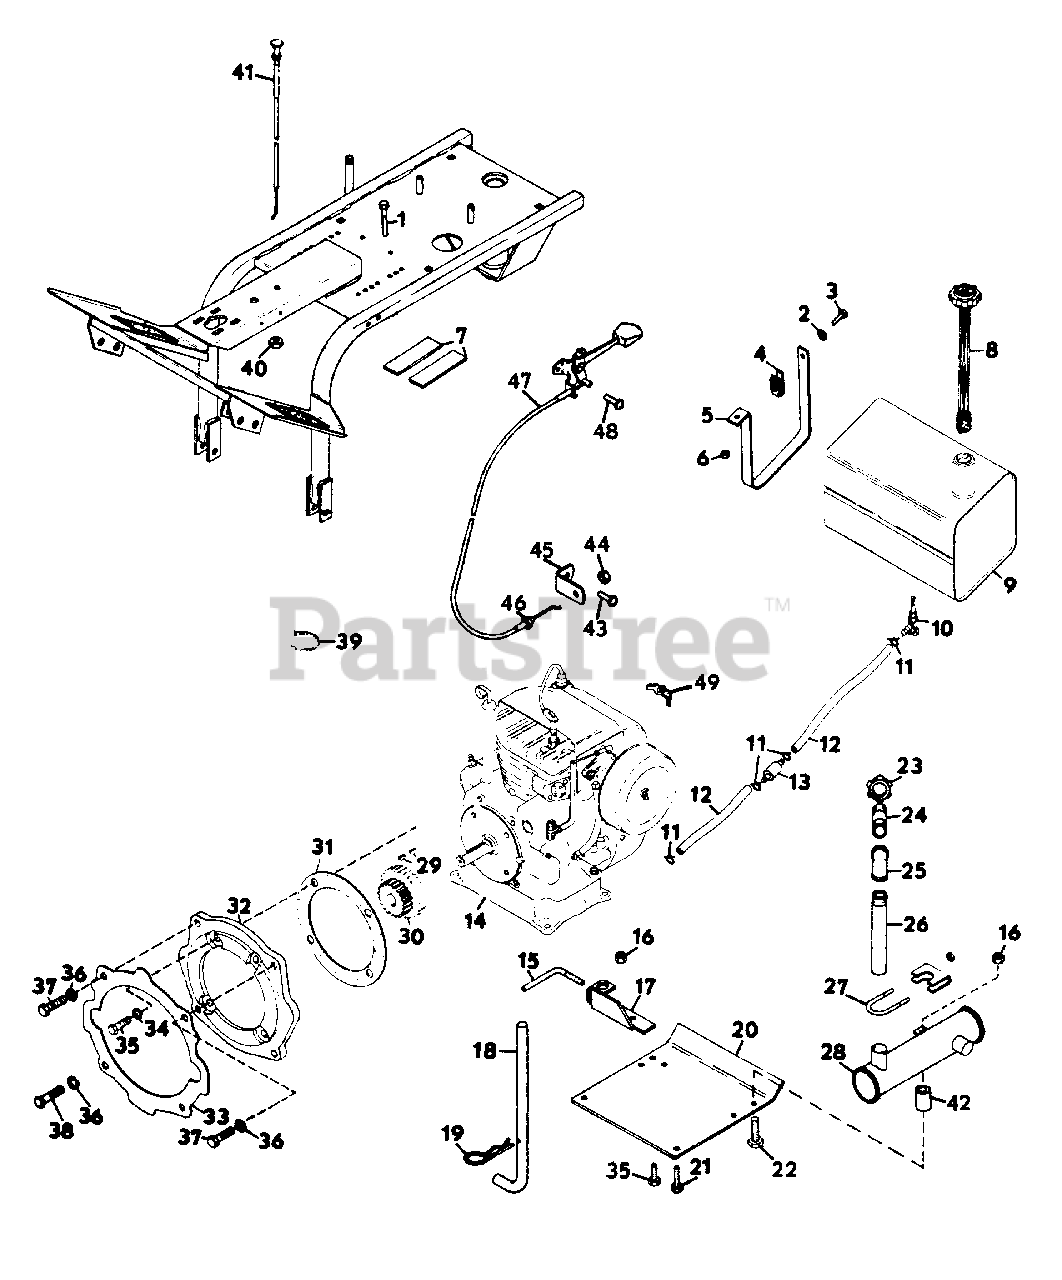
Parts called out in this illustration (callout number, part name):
1	BOLT, HEX 5/16-18X1.25
2	WASHER, FLAT .312X.734X.065
3	BOLT, HEX 5/16-18X.75
4	NUT, RETAINER
5	STRAP, GAS TANK
6	NUT, LOCK 5/16-18
7	PAD, GAS TANK
8	GAUGE, FUEL
9	TANK, FUEL
10	VALVE AND STRAINER
11	CLAMP, FUEL HOSE
12	LINE, FUEL
13	FILTER, FUEL
14	ENGINE, 16-HP KOHLER
15	HANDLE, ADJUSTING
16	NUT, LOCK 3/8-16
17	STAND, SUPPORT
18	STAND, KICK
19	PIN, HAIR
20	PLATE, SKID
21	BOLT, HEX 3/8-16X1.50
22	BOLT, HEX 3/8-16X1.75
23	NUT, CONDUIT 1.25" PIPE
24	NIPPLE, 1.25 PIPE
25	ELBOW, 1.25 PIPE
26	NIPPLE, 1.25 PIPE 8.6 LG.
27	CLAMP, MUFFLER
28	MUFFLER, 16-HP ENGINE
29	KEY, WOODRUFF 5/32X.625
30	GEAR, 10/12 DP 21/30 TEETH
31	GASKET, ENGINE TO ADAPTOR
32	ADAPTOR, ENGINE
33	GASKET, CHASSIS TO ADAPTOR
34	WASHER, LOCK 3/8
35	BOLT, HEX 3/8-16X1.00
36	WASHER, LOCK 7/16
37	BOLT, HEX 7/16-14X1.50
38	BOLT, HEX 7/16-14X1.25
39	TIE, CABLE
40	NUT, JAM 3/8-24 HEX
41	CONTROL, CHOKE
42	BUSHING, .407X.625X.812
43	SCREW, MACH. 1/4-20X.50
44	NUT, HEX 1/4-20
45	BRACKET
46	ADAPTOR, CONDUIT
47	LEVER, CONTROL
48	SCREW, TAPPING 1/4-20X.50 PAN
49	CLIP, SPEED
